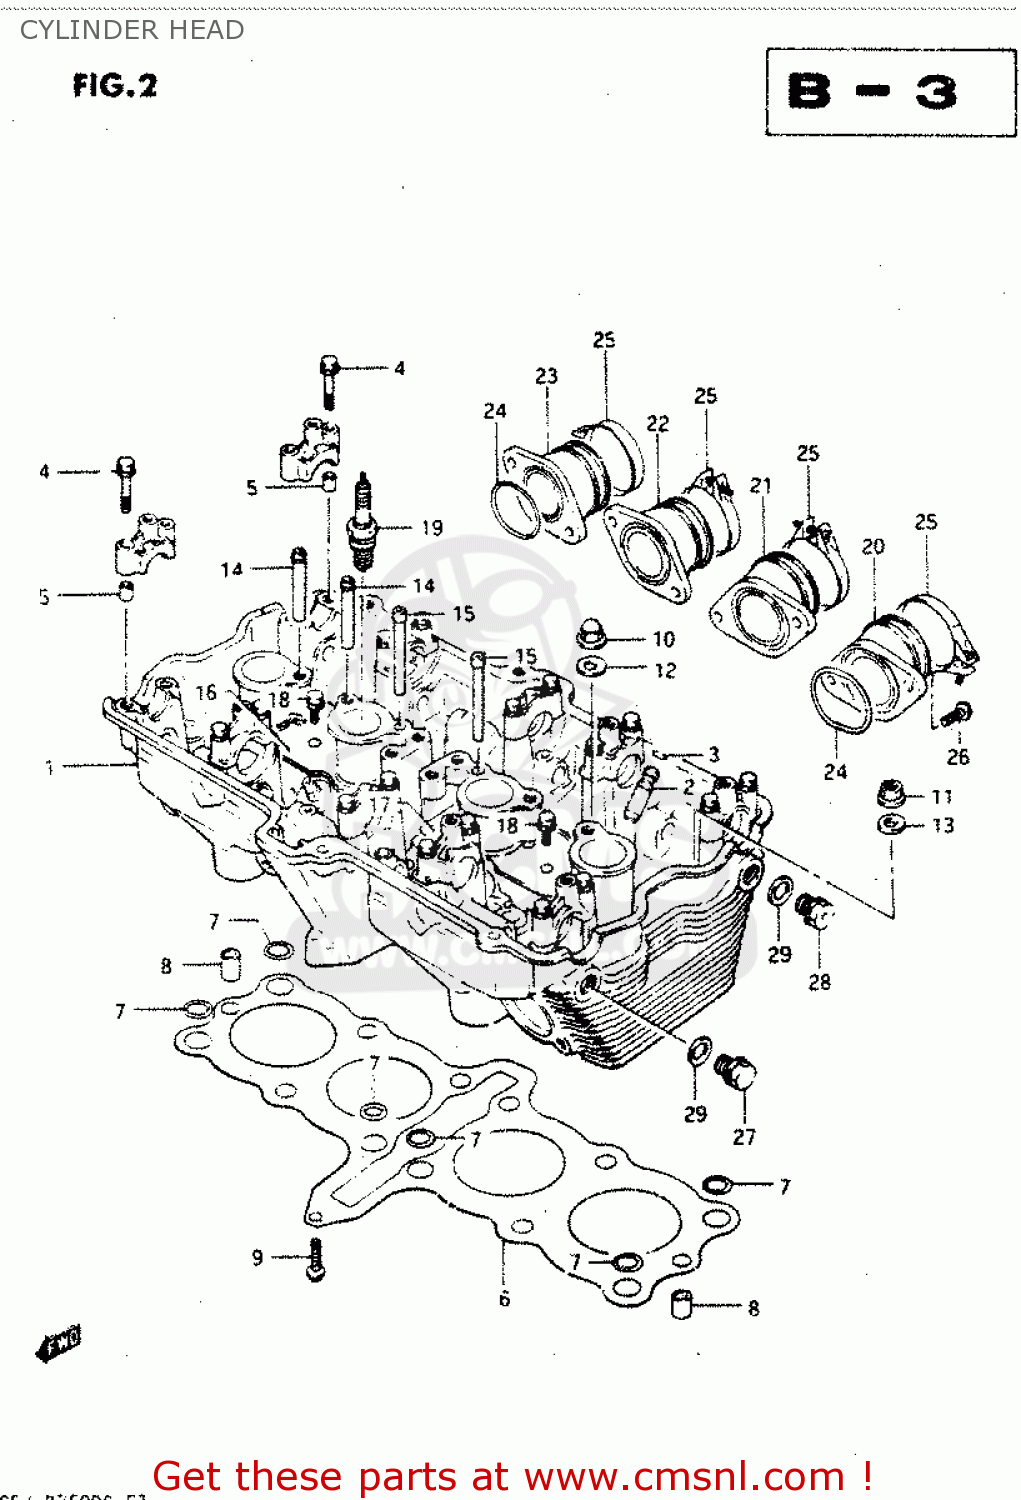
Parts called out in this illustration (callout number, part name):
1	HEAD ASSY, CYLINDER
2	GUIDE,VALVE
3	RING,SNAP
4	BOLT(6X39)
5	PIN(6.2X8X11)
6	GASKET,CYLINDER HEAD (NAS)
7	O RING(D:2.4,ID:12.3)
8	PIN
9	BOLT
10	NUT
11	NUT
12	GASKET(10.2X20X2).3 (NAS)
13	WASHER (10.5X22X2.3)
14	PIPE,OIL NO.1
15	PIPE,OIL NO.3
16	PLATE,OIL PIPE,R
17	PLATE,OIL PIPE,L
18	BOLT
19	SPARK PLUG D9EA
20	PIPE,INTAKE
21	PIPE,INTAKE
22	NET,INTAKE
23	PIPE,INTAKE
24	O RING(D:2.4,ID:39.7)
25	CLAMP
26	SCREW
27	PLUG
28	PLUG
29	GASKET(14X19.2X2) (NAS)
